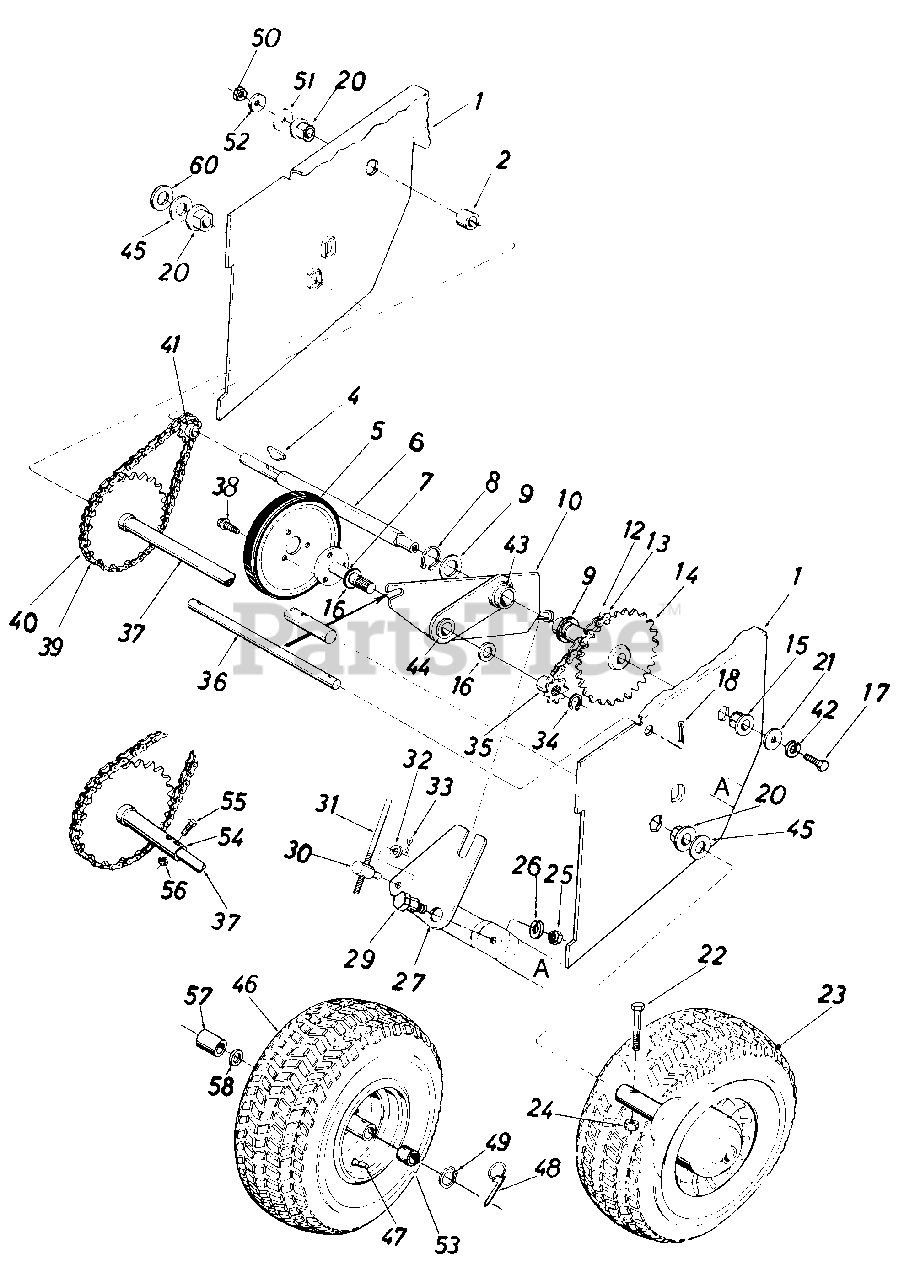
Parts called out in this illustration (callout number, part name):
1	Frame Ass'y.
2	Spacer .50" I.D. x 75" O.D. x.78" Lg.
4	#4 Hi-Pro Key 3/32 x 5/8" Dia.
5	Friction Wheel Ass'y.
6	Hex Shaft
7	Friction Wheel Mounting Plate Ass'y.
8	Snap Ring 1.00" Dia. Shaft
9	Fl-Wash. 1.00" x 1.63" O.D. x .03
10	Sliding Bracket Ass'y.
12	#41 Chain 1/2" Pitch x 35 Links
13	Master Link for #41 Chain
14	32 Teeth Sprocket Ass'y.
15	Hex Flange Brg. .630" I.D.
16	Fl-Wash. .62n I.D. x 1.00" O.D. x .06
17	Hex Lock Bolt 5/16-18 x .62" Lg.
18	Cotter Pin 3/32" Dia. x .75" Lg.
20	Flange Brg. w/Flats .75" I.D.
21	Fl-Wash. 34" I.D. x 1.12" O.D. x .125
22	Hex Bolt 5/16-24 x 1.50" Lg.
23	Wheel Ass'y.
24	Hex Ins. Jam L-Nut 5/16-24 Thd.
25	Hex Jam Nut 3/8-16 Thd.
26	L-Wash. 3/8" I.D.
27	Shifting Linkage Bracket
29	Shld. Bolt .625" Dia. x .170" Lg.
30	Adjustment Ferrule
31	Shifting Rod 5/16" Dia. x 32.50" Lg.
32	Fl-Wash. .34" I.D. x .64" O.D. x .06
33	Cotter Pin 3/32" Dia. x 75" Lg.
34	Snap Ring .562" Dia. Shaft
35	Sprocket 7 Teeth x 50" Pitch
36	Shaft 50" Dia. x 9.50" Lg.
37	28 Teeth Wheel Axle Ass'y.
38	Hex Wash. Hd. Self-Tap Scr. 5/16-24 x .50" Lg.
39	#41 Chain 1/2" Pitch x 43 Links
40	Master Link for #41 Chain
41	8 Teeth Center Sprocket
42	L-Wash. 5/16" I.D.
43	Bearing
44	Bronze Bearing
45	Fl-Wash. .76" I.D. x 1.49 O.D.
46	Wheel Assembly
47	Air Valve
48	Klick Pin
49	Snap Ring .75 Dia.
50	Hex Ins. L-Nut 1/2-20 Thd.
51	Fl-Wash. .53 I.D. x 1.25 O.D. x .10
52	Bell-Wash. .50 I.D. x 1.0 O.D. x .075
53	Sleeve Brg.
54	32 Teeth Sprocket Hub Ass'y.
55	Hex Bolt 1/4-28 x 1.5"
56	Hex L-Nut 1/4-28 Thd.
57	Spacer
58	Fl-Washer
60	Fl-Washer
